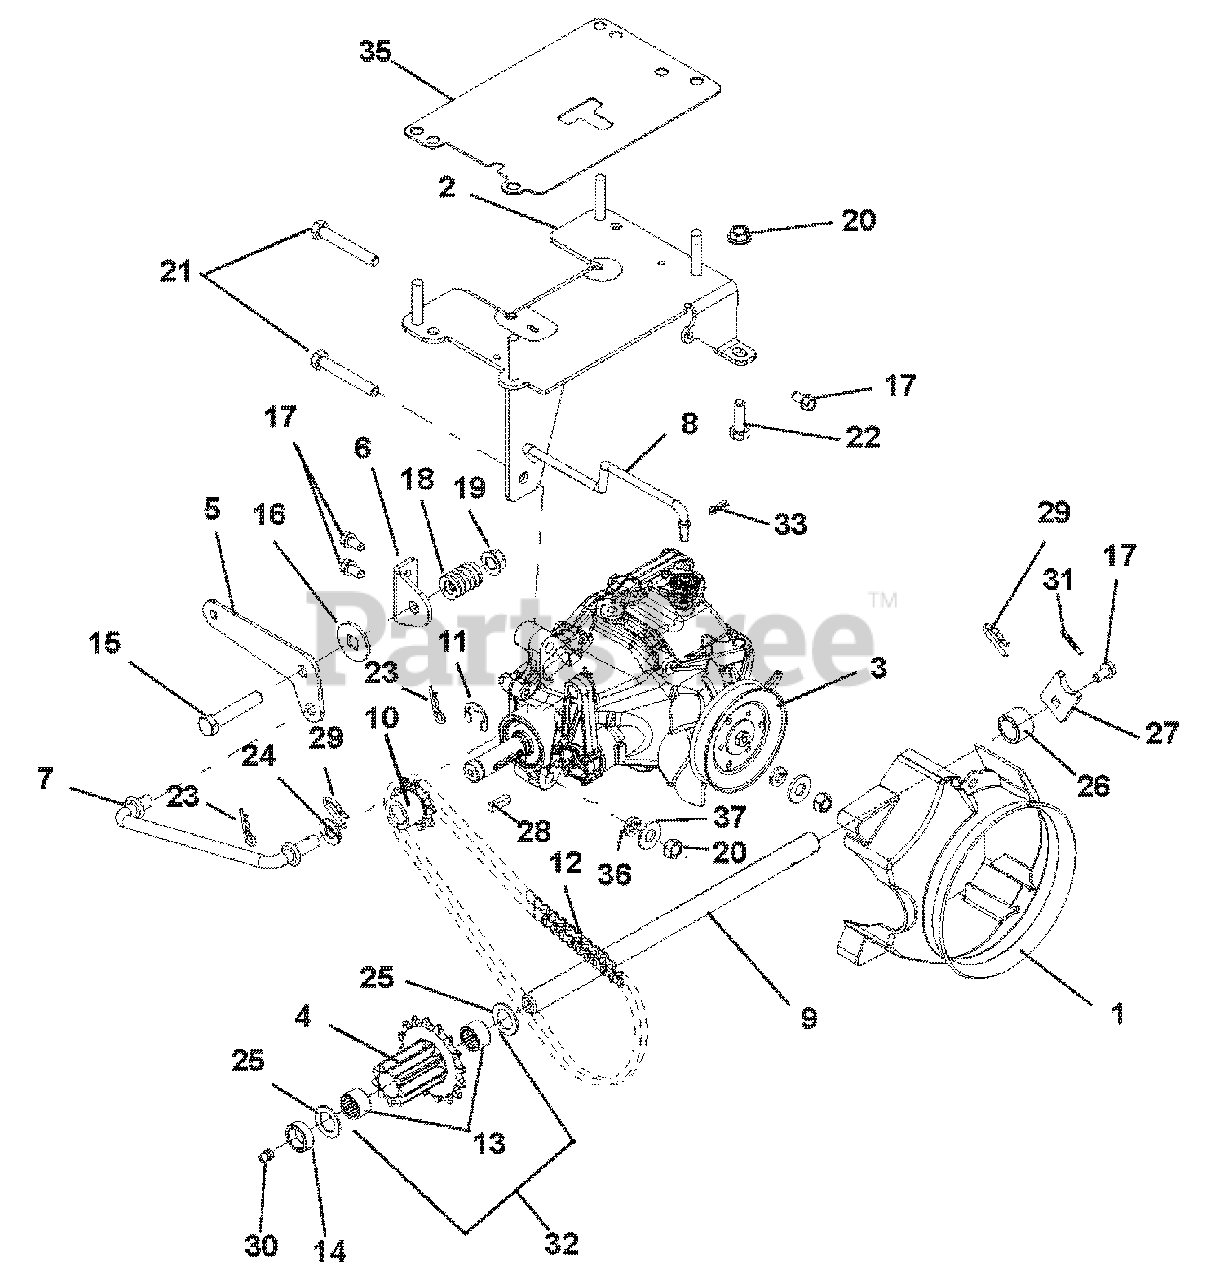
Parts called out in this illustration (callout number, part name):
1	SHROUD, HYDROGEAR RT-310
2	BRACKET, HYDROSTATIC TRANS XLG
3	TRANSMISSION, HYDROSTATIC
4	PINION & SPROCKET
4	PINION & SPROCKET (16T & 9T)
5	PIVOT, HYDRO TRANS SHIFT
6	BRACKET, HYDRO SHIFT PIVOT
7	ROD, HYDRO TRANS SHIFT
8	ROD, HYDRO BYPASS
9	SHAFT, PINION - HARDENED
10	SPROCKET, PINION 9T W/KEY
11	RG-RTNG-EXT .625X.042
12	CHAIN - #41, 32 PITCHES
12	CHAIN-ROLLER #41X26 PITCHES
13	BSHG-FLG .625X.750X.500X.875
13	BRG-NEEDLE .625X.812X.50
14	BSHG-SLV, .635X.880X.305
15	@BLT-HEX .38-16X2.00 GR5 YWZC
16	FRICTION WASHER
17	SCR-TAP .25-20X.50 HWH TR YWZ
18	SG-COMP .187X.56X1.62
19	@NUT-LK-TOP-FLG .38-16 YWZC
20	@NUT-LK-TOP-FLG .31-18 YWZC
21	@BLT-HEX .31-18X2.25 GR5 YWZC
22	@BLT-HEX .31-18X1.00 GR5 YWZC
23	PIN-HAIR INT .08X.18X1.18 YWZC
24	@WSHR-FL-STL.406X.812X.065 YWZ
25	WSHR-FL-STL .630X1.005X.062 YZ
26	SPACER, .635X.880X.611
27	TAB, ANTI ROTATION
28	KEY-SQ .188X.75X.188
29	PIN, SPRING CLIP
30	ZERK,FITTING .25X.125 DRIVE IN
31	@PIN-GRV .125X1.00 TP E ALLOY
32	PINION & SPROCKET W/BUSHINGS
32	PINION & SPROCKET W/BEARINGS
33	PIN-HAIR INT .06X.18X.77
34	@NUT-HEX .31-18 YWZC
35	SPACER, TRANSMISSION MOUNT
36	@WSHR-FL-STL.38X.875X.083 YWZC
37	WSHR-LK .312X.097 HVY YWZC
